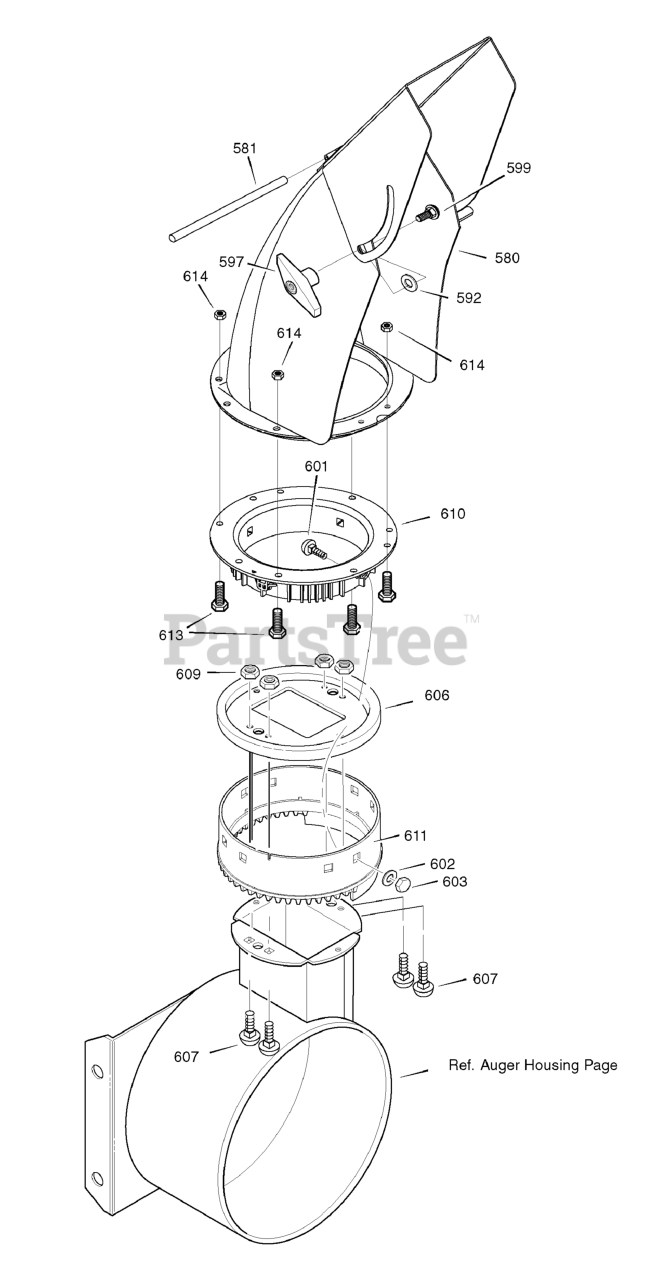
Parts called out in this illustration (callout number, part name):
580	CHUTE ASSEMBLY
592	WASHER, PLASTIC
597	KNOB, T 3.00
599	BOLT, Carriage, 5/16-18 x 1-1/2
601	CARRIAGE BOLT, 5/16-18 x 1.00
602	WASHER
603	NUT, Hex, Nylock, 5/16-18
606	CHUTE COLLAR
607	BOLT, CARRIAGE 1/4-20 X 0.75
609	NUT, 1/4-20 HEX NYLOCK
610	RETAINER RING INNER
611	RETAINER RING OUTER
613	BOLT, Carriage, Hex Flange Head, 1/4-20 x 3/4
614	NUT, Nylock Flanged, 1/4-20
